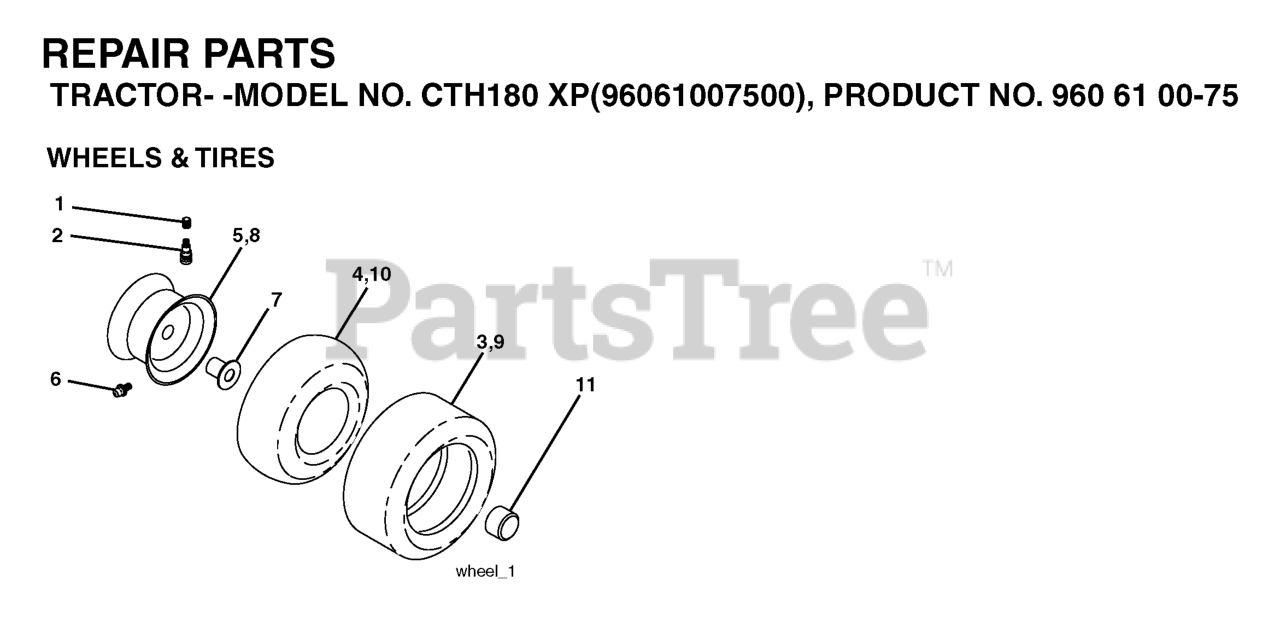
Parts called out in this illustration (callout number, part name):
2	VALVE STEM LT
3	TIRE HEAVY DUTY
4	TUBE.5.3/4.5/6
5	RIM ASM 6" FRONT SILVER
6	FITTING LT
7	BEARING T
8	RIM ASM 8" REAR SILVER
9	TIRE.TS.20X10-8
10	TUBE
11	CAP, AXLE BLK
